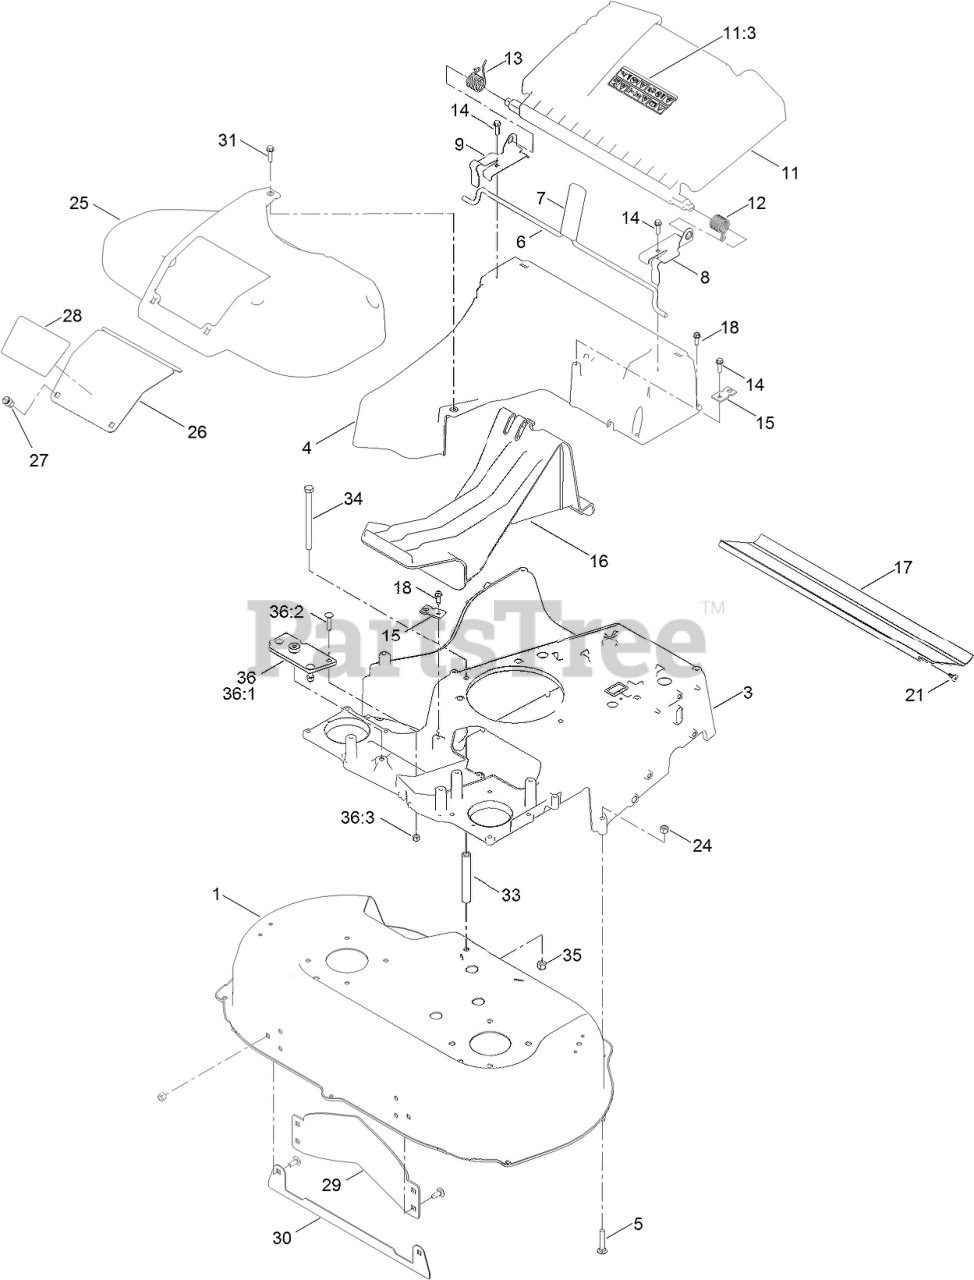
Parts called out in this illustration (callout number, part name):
1	HOUSING ASM
3	FRAME
5	BOLT-CAR
6	ROD-RELEASE, HANDLE
7	GRIP-LEVER
8	BRACKET-DOOR, LH
9	BRACKET-DOOR, RH
11	REAR DEFLECTOR ASM
11:3	DECAL-WARNING
12	SPRING-TORSION
13	SPRING-TORSION
14	SCREW-PLASTITE, HWH
15	BRACKET-CABLE, TRACTION
16	PLUG-MULCH
17	SHIELD-TRAILING
18	SCREW-HWHTF
21	SCREW-THD
24	NUT-HEX
25	COVER-BELT
26	DOOR-ACCESS
27	FASTENER
28	DECAL-ACCESS PANEL
29	BAFFLE-CONTROL
30	PLATE-DECK
31	SCREW-HWHTF
33	SPACER-SHIELD
34	SCREW-HH
35	NUT-HEX
36	FRAME PLATE KIT
36:1	PLATE-FRAME
36:2	SCREW-CARR
36:3	NUT-LOCK, NI
